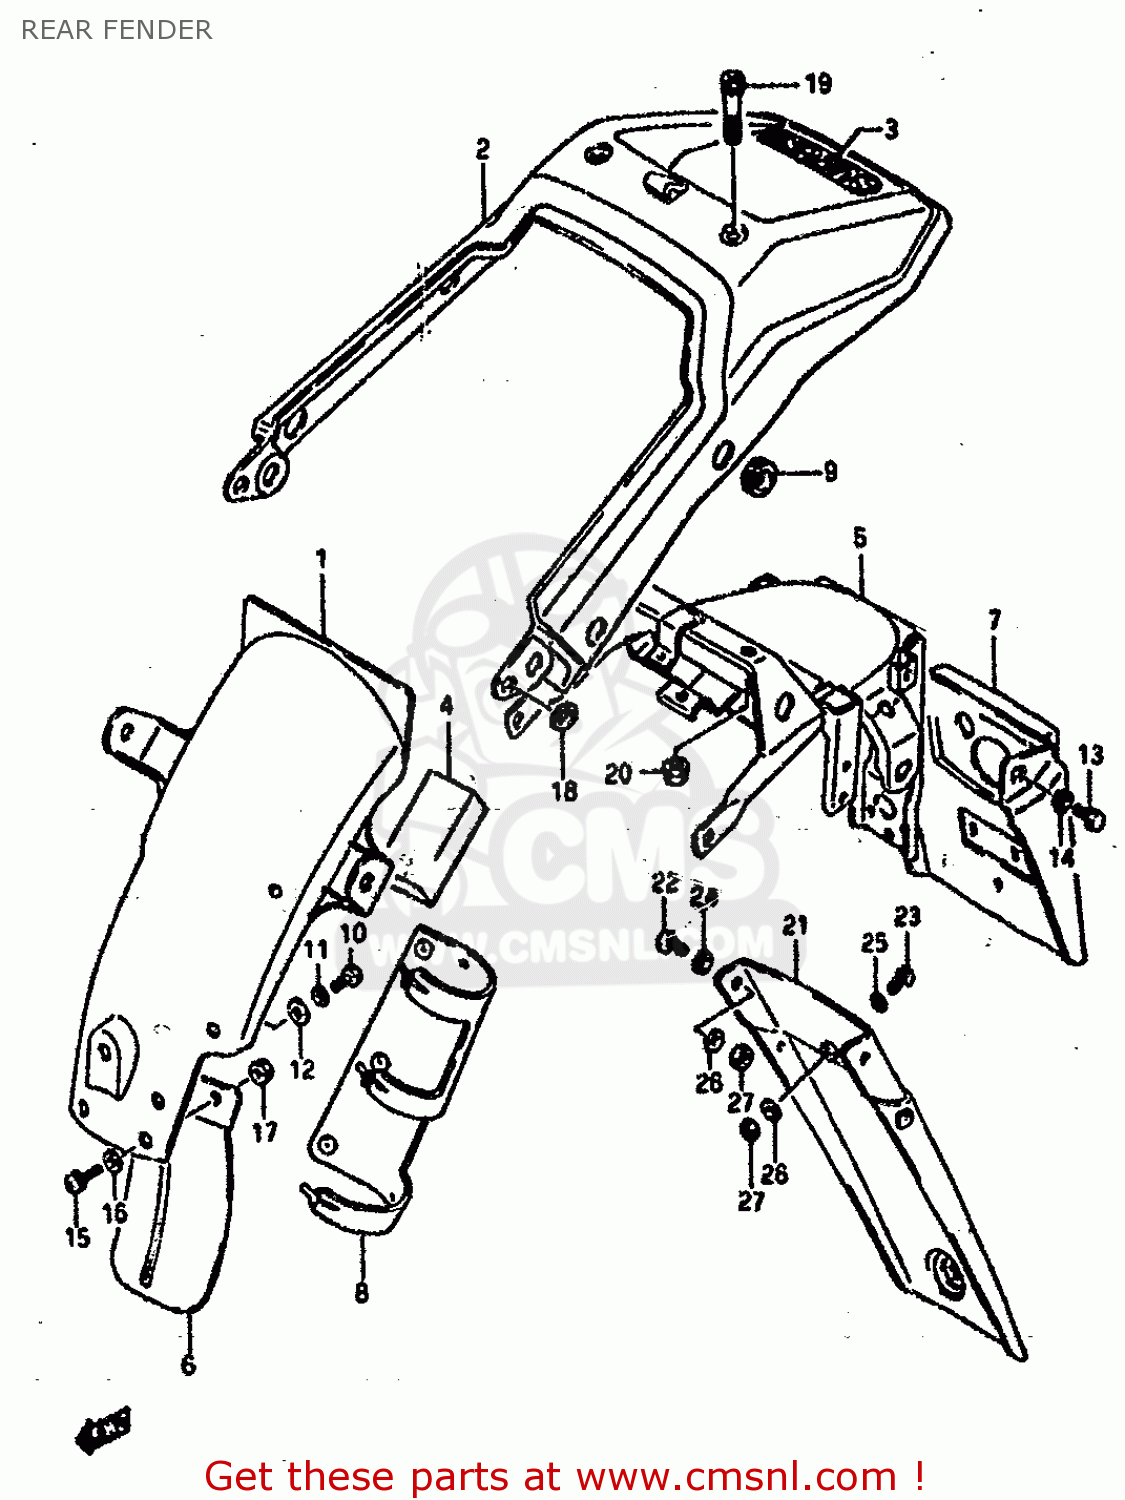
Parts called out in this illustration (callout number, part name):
1	BODY,REAR FENDER FRONT
2	BODY,REAR FENDER REAR (RED)
3	EMBLEM
4	DUST SEAL,REAR FENDER
5	REINFORCEMENT,REAR FENDER
6	GUARD,REAR FEN
7	EXTENSION,REAR FENDER
8	GUARD,MUD
9	GROMMET
10	BOLT 6X16
11	WASHER,LOCK
12	WASHER
13	BOLT
14	WASHER
15	SCREW
16	WASHER
17	NUT
18	WASHER
19	BOLT
20	NUT
21	MUD GUARD,REAR FENDER
22	SCREW 6X12
23	SCREW(6X25)
24	WASHER
25	WASHER,LOCK
26	WASHER(6.5X16X1.2)
27	NUT
